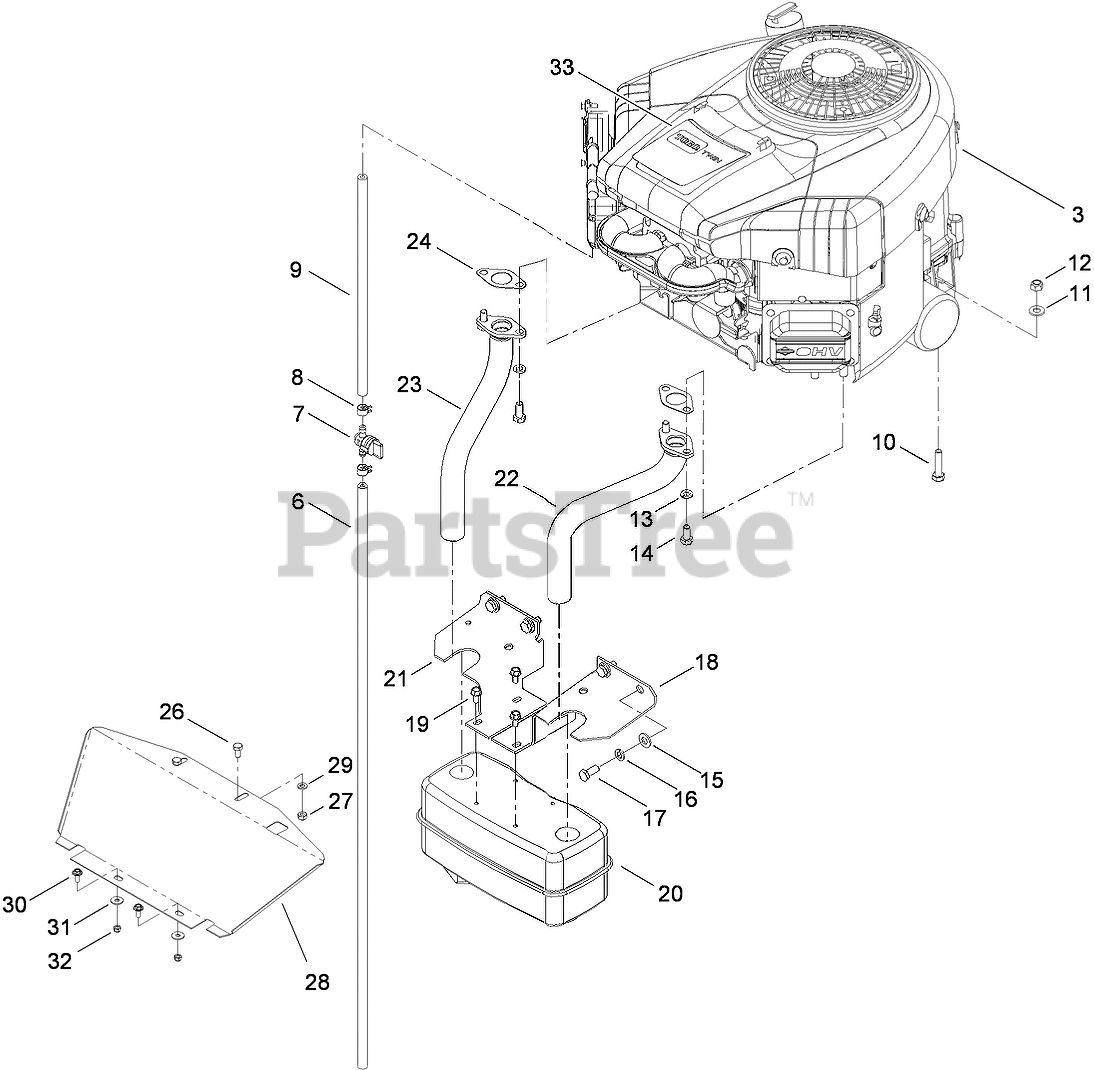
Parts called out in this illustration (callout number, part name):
6	LINE-FUEL
7	VALVE-TANK, FUEL
8	CLAMP-LINE, FUEL
9	LINE-FUEL
10	SCREW-HH
11	WASHER-PLAIN
12	NUT-LOCK, NI
13	WASHER-SPRING
14	SCREW-HH
15	WASHER-PLAIN
16	WASHER-SPRING
17	SCREW-HH
18	GUARD-MUFFLER, LH
20	MUFFLER
21	GUARD-MUFFLER, RH
22	TUBE-EXHAUST, LH
23	TUBE-EXHAUST, RH
24	GASKET-EXHAUST
26	SCREW-HH
27	NUT-LOCK
28	SHIELD-HEAT
29	WASHER-FLAT
31	WASHER-FLAT
32	NUT-LOCK
33	DECAL-ENGINE
